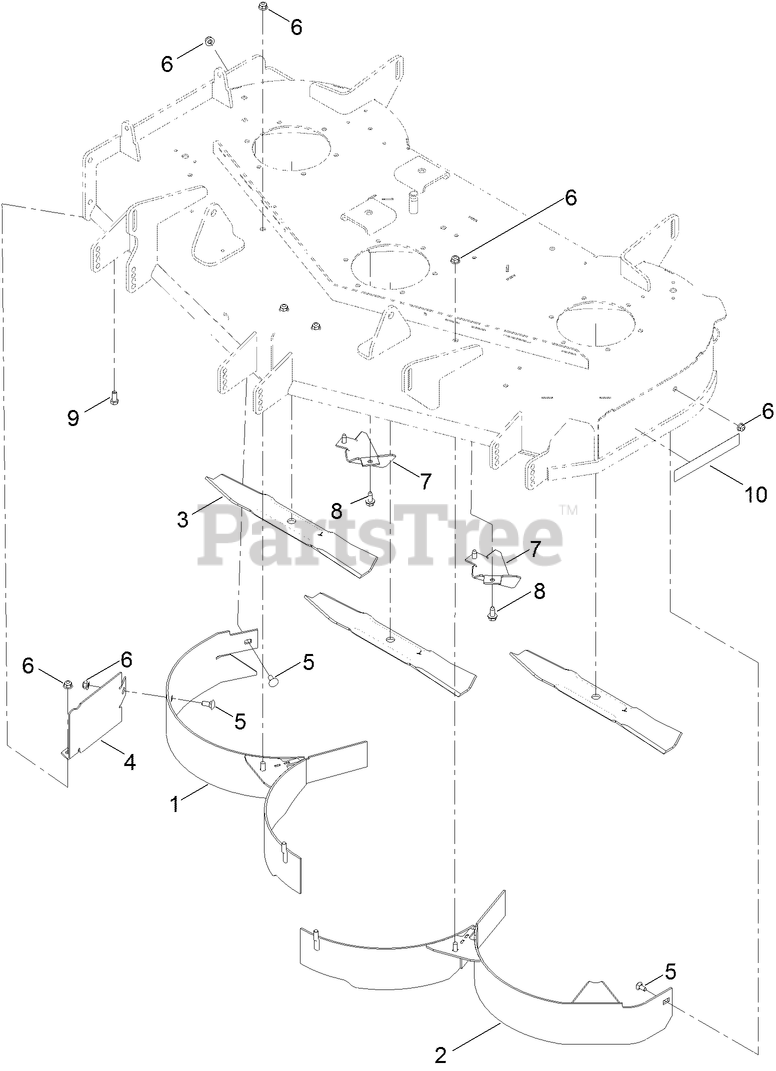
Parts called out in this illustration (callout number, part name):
1	BAFFLE-RECYCLER
2	BAFFLE-RECYCLER
3	BLADE-MULCH, 16.50 INCH
4	GUARD-BAFFLE
5	BOLT-CARR
6	NUT-HF, NI
7	KICKER-FLANGED
8	SCREW-HWHTF
9	SCREW-HH
10	DECAL-RECYCLER
